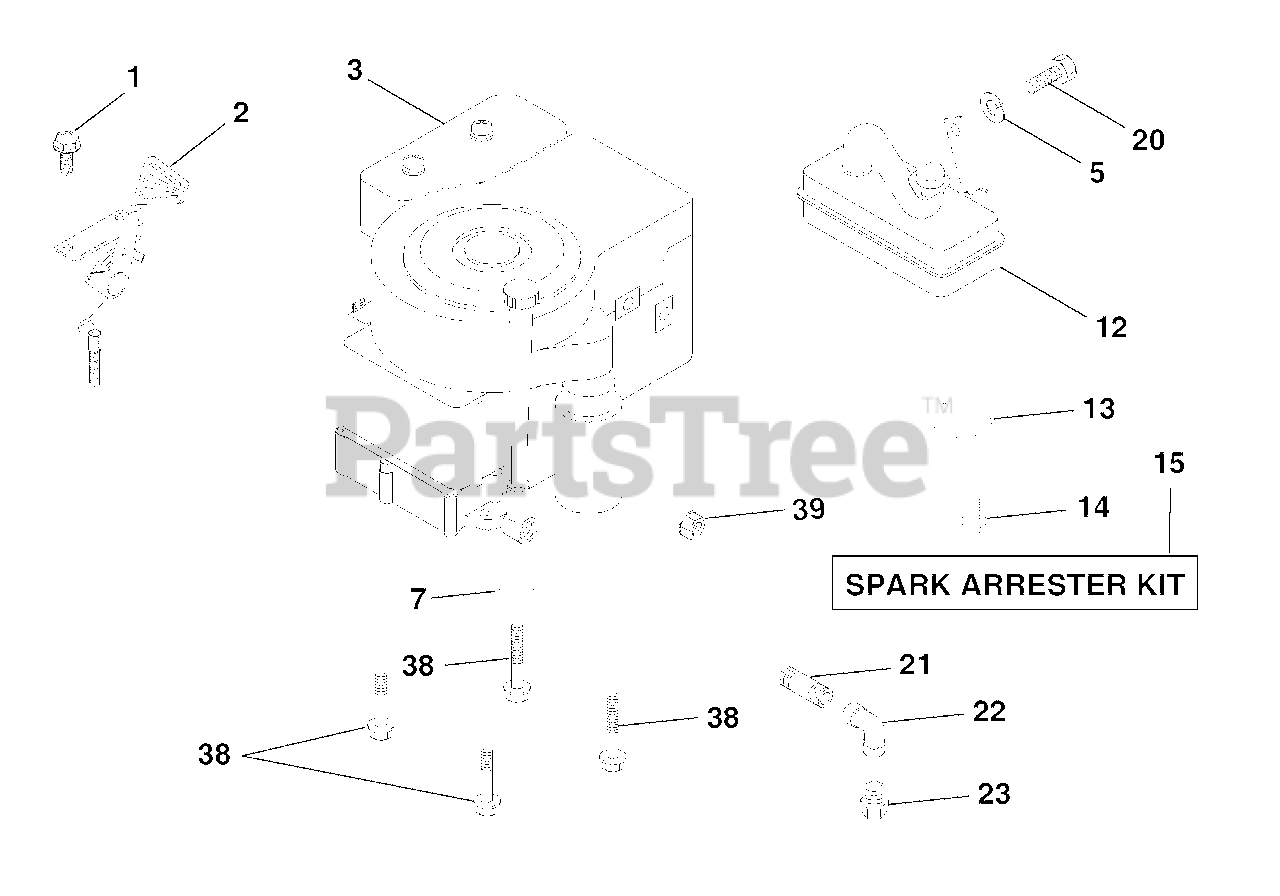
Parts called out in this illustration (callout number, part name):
1	Screw, Head Head, Thread Cutting 1/4-20 x 1/2
2	Control, Throttle
5	Washer, Lock, Heavy Helical Spring 5/16
7	Washer, Lock Ext. Tooth 3/8
13	Deflector, Muffler
14	Screw, Spiderlock
15	Arrester, Spark
20	Bolt, Hex Hd. 5/16-18 x 1/2
21	Nipple, Pipe 3/8 NPT x 3-1/2
22	Elbow, STD 90 Degree 3/8-18 NPT
23	Nipple, Pipe
38	Bolt, Hex
39	Nut Keps Hex 1/4-20
